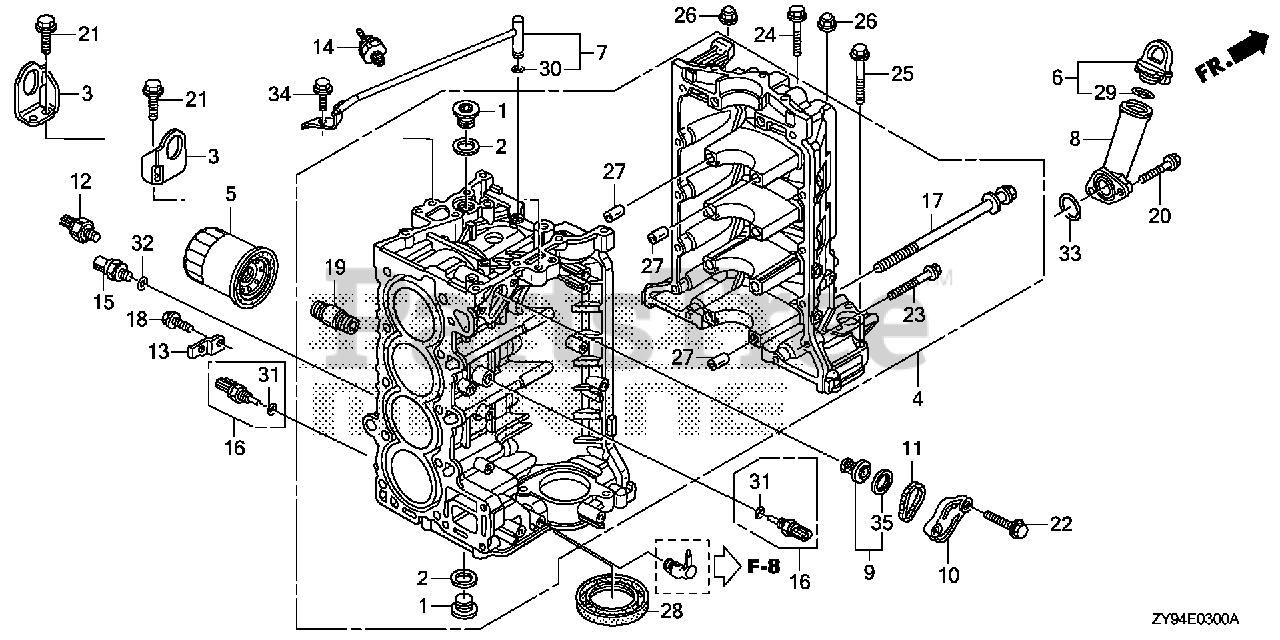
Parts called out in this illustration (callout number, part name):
1	BOLT, SEALING (24MM)
2	WASHER, SEALING (24MM)
3	HANGER, ENGINE
4	BLOCK ASSY., CYLINDER *NH8* (DARK GRAY)
5	FILTER, OIL (FILTECH TOYO ROKI) (SOLD IN MULTIPLES OF 30)
5	FILTER, OIL (FILTECH TOYO ROKI) (SOLD INDIVIDUALLY)
5	FILTER, OIL
6	CAP ASSY., OIL FILLER
8	EXTENSION, OIL FILLER
9	THERMOSTAT ASSY.
10	COVER, THERMOSTAT
11	O-RING, THERMOSTAT COVER
13	BRACKET, CLIP B
14	SWITCH ASSY., OIL PRESSURE
15	SWITCH ASSY., OIL PRESSURE
16	SENSOR ASSY., WATER TEMPERATURE
17	BOLT-WASHER (10X105)
18	BOLT, FLANGE (6X14) (CT200)
19	HOLDER, OIL FILTER
20	BOLT, FLANGE (6X25)
21	BOLT, FLANGE (8X20)
22	BOLT, FLANGE (6X22)
23	BOLT, FLANGE (6X32)
24	BOLT, FLANGE (8X35)
25	BOLT, FLANGE (8X45)
26	NUT, FLANGE CAP (8MM)
27	PIN, DOWEL (12X14)
28	OIL SEAL (80X98X10)
28	OIL SEAL (80X98X10) (ARAI)
29	O-RING (18.1X3.6)
30	O-RING (6.5X1.5)
31	O-RING (9.5X1.9)
32	O-RING (13X1.5) (ARAI)
33	O-RING (28.3X2.4) (NOK)
34	BOLT, FLANGE (6X14)
35	RUBBER, RING
